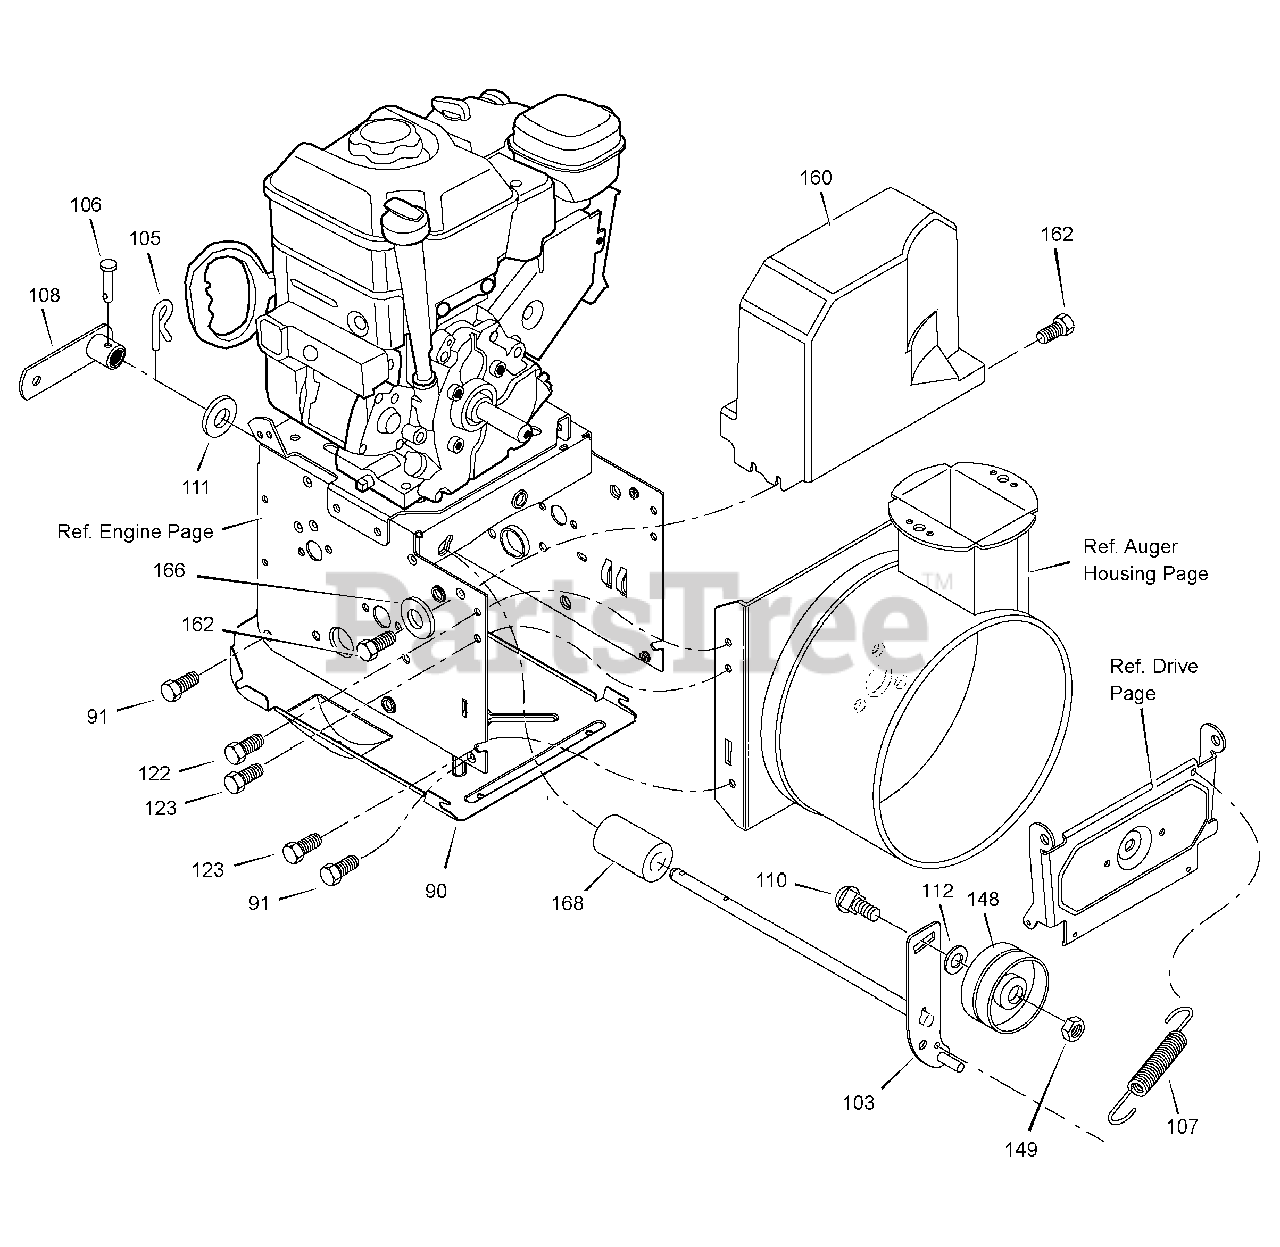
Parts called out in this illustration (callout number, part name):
90	COVER, BOTTOM
91	SCREW, 1/4-20X .63
103	IDLER ASSEMBLY, AUGER
105	PIN, HAIR .38DIAX1.64LG
106	PIN, CLEVIS 3/16" DIA
107	SPRING, TENSION
108	ARM, CONTROL
110	BOLT, 3/8-16X1.25 CARR.
111	WASHER, FLAT
112	WASHER
122	SCREW, TAP 5/16-18 X 0.50
123	SCREW, TAP 5/16-18 X 0.75
148	PULLEY, IDLER
149	NUT, JAM 3/8-16
160	COVER, BELT
162	SCREW, TAP
166	WASHER, FLAT
168	SPACER, AUGER BRACKET
